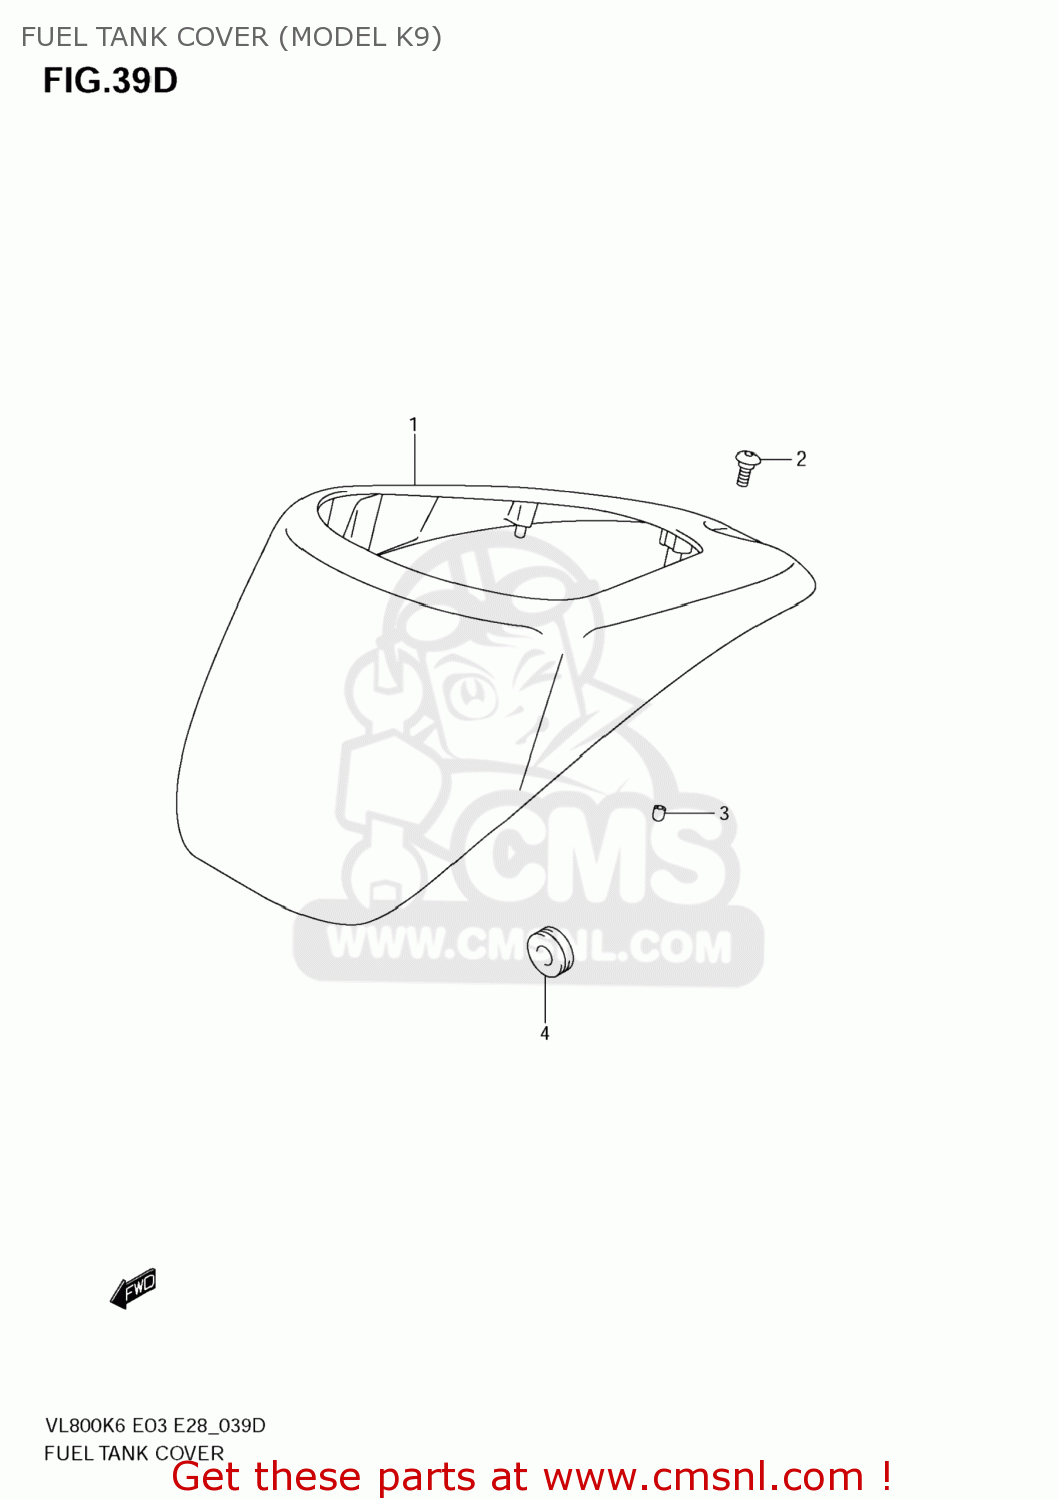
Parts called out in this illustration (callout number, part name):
1	COVER,FUEL TANK UPR
2	SCREW(5X13)
3	CUSHION,FUEL TANK COVER
4	CUSHION
